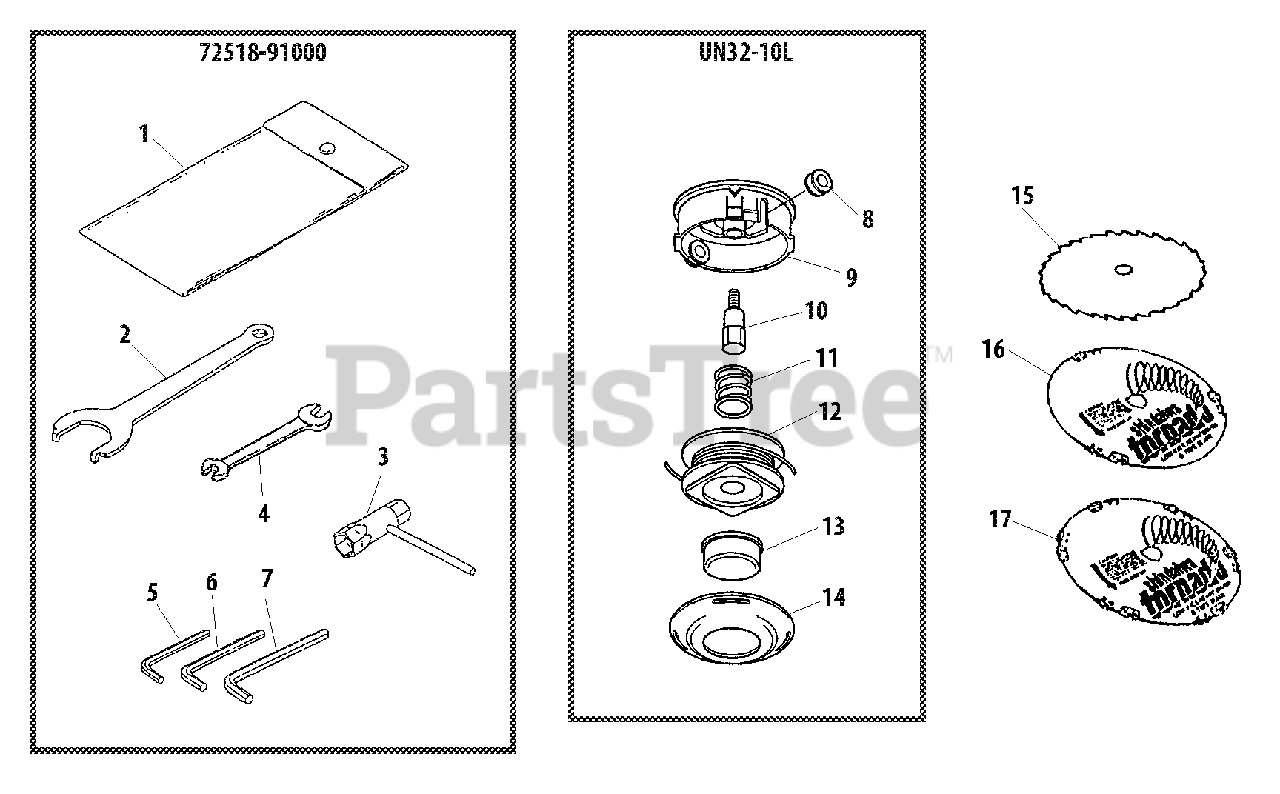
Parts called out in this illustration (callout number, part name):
1	BAG, TOOL
2	SPANNER
3	T-WRENCH 17×19 MM
4	SPANNER 8×10
5	WRENCH, ALLEN 3 MM
6	WRENCH, ALLEN 4 MM
7	WRENCH, ALLEN 5 MM
10	SHAFT BOLT 10 MM LH
15	BLADE - 30 TOOTH -- 9"
16	BLADE - 6 TOOTH -- 9" TORNADO
17	BLADE - 12 TOOTH -- 9" TORNADO
72518-91000	SERVICE TOOL KIT
UN32-10L	TRIMMER HEAD ASSY
